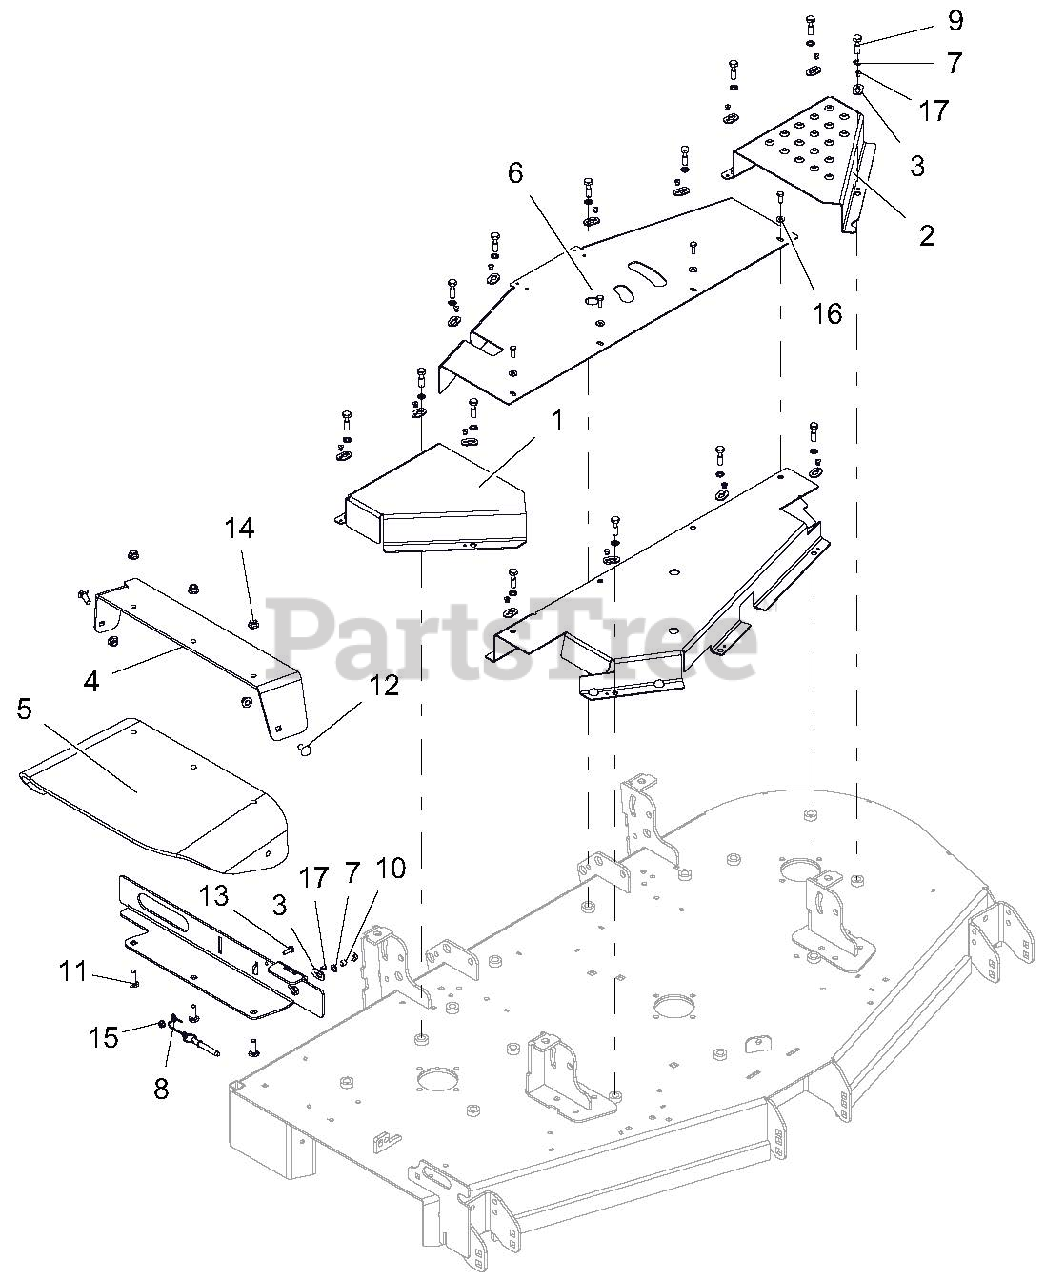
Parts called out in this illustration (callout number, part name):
1	GUARD, RH PT200 CE BELT
2	GUARD, LH PT200 CE BELT
3	KEEPER, BOLT
4	SUPPORT, CHUTE MOUNTING BRACKET-RED
5	CHUTE, RUBBER DISCHARGE
6	BRKT, REAR BELT GUARD CE-60
7	LOCK, WSHR-EXT 0.391 X 0.628 X 0.036 YWZC
8	CABLE, 6.0 LANYARD, NYLON
9	BLT, HEX 0.38-16 X 1.25 GR5 CAPTIVE
10	BLT-HEX .38-16X1.25 GR5 CAP .37
11	BLT-RDHDSQNK .38-16X1.25 G5 YWZC
12	BLT-RDHDSQNK .38-16X1.00 G5 YWZC
13	BLT-HEX .25-20X.75 GR5 YWZC
14	NUT-LK-NYL-FLG .38-16 YWZC
15	NUT, LK-TOP-FLG .25-20 YWZC
16	WSHR-FL-STL.281X.62X.065 YWZC
17	RVT-POP .187x.250 (#64) YWZC
